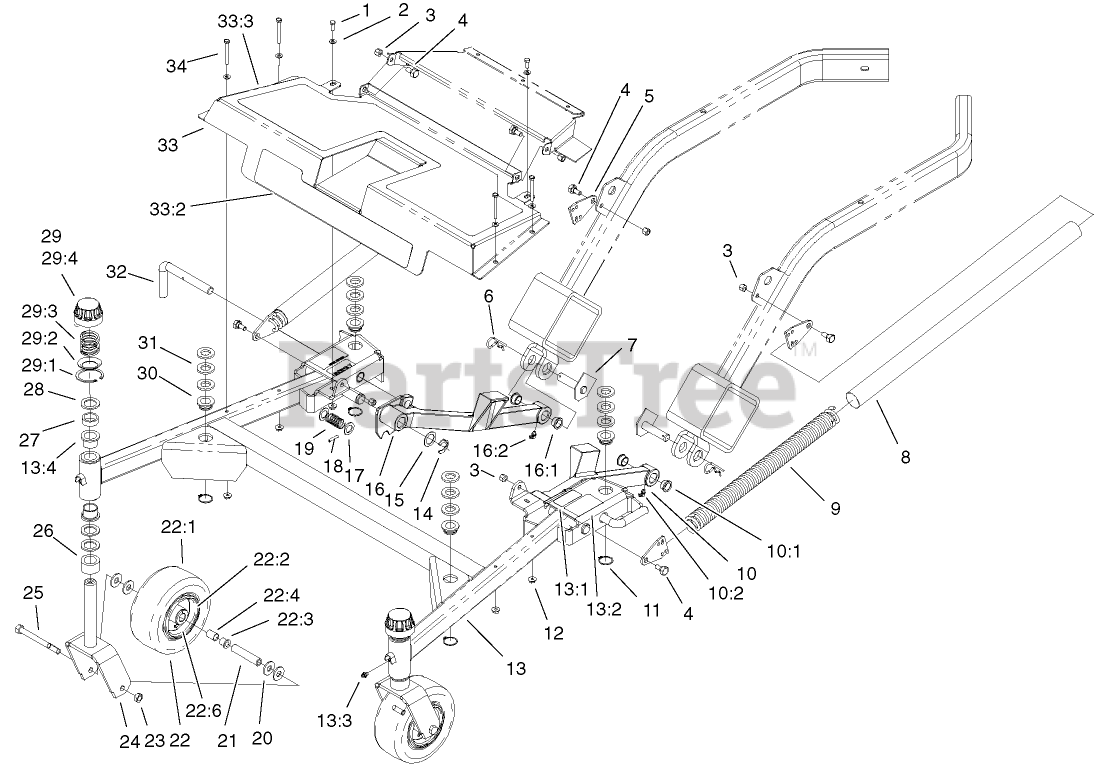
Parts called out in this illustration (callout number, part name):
1	SCREW-HH
2	WASHER-FLAT
3	NUT-LOCK, NI
4	BOLT-SHOULDER
5	PLATE-END, SPRING
6	PIN-HAIR
7	PIVOT PIN ASM
8	COVER-SPRING
9	SPRING-EXTENSION
10	LH PUSHARM ASM
10:1	BEARING-FLANGE
10:2	FITTING-GREASE
11	RING-RETAINING
12	NUT-HF
13	CARRIER FRAME ASM
13:1	DECAL-WARNING
13:2	DECAL - HOC, CE
13:3	FITTING-GREASE
13:4	BUSHING
14	RING-RETAINING
15	Washer
16	RH PUSHARM ASM
16:1	BEARING-FLANGE
16:2	FITTING-GREASE
17	WASHER
18	PIN-ROLL
19	SPRING-COMPRESSION
20	WASHER-FLAT
21	SPANNER-TIRE
22	CASTOR WHEEL ASM
22:2	RIM ASM
22:3	BEARING-OUTSIDE
22:4	BEARING-ROLLER
22:6	FITTING-LUBE, 45 DEG
23	NUT-HEX
24	CASTOR FORK ASM
25	SCREW-HH
26	SPACER-CASTOR
27	SPACER
28	WASHER-THRUST
29	HOC CAP ASM
29:1	RING-RETAINING
29:2	WASHER-CAP
29:3	SPRING-COMPRESSION
29:4	CAP-HOC
30	BUSHING-DECK
31	WASHER-FLAT
32	PIN-PIVOT
33	FOOTREST ASM
33:3	PAD-FOOTREST
34	SCREW-HH
